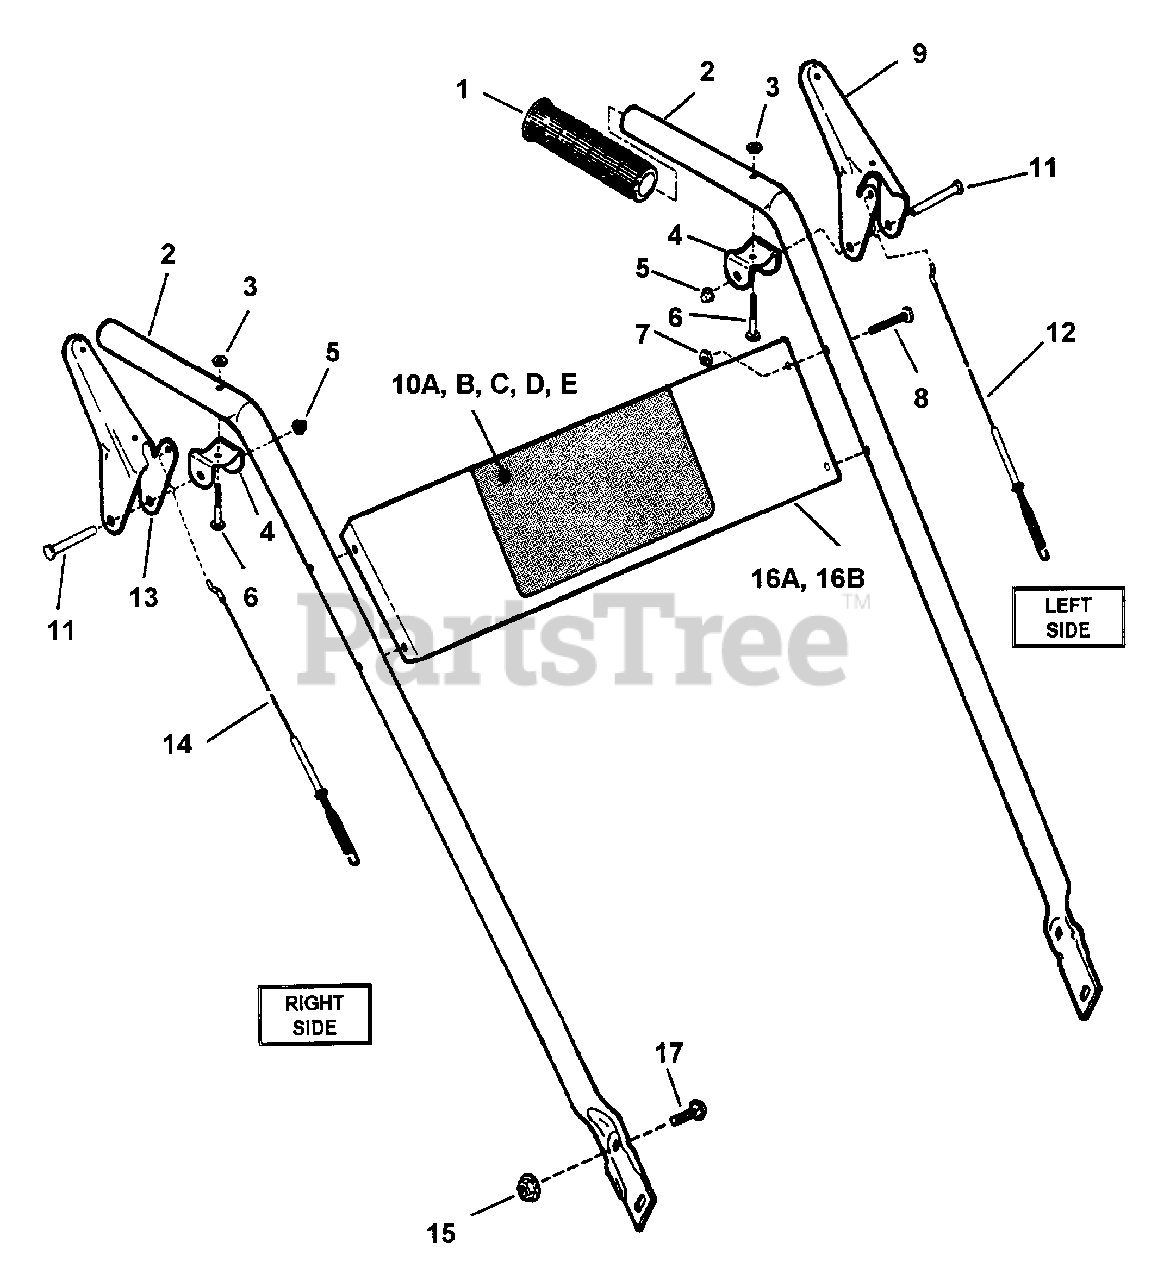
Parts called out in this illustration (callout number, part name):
1	GRIP, Handle
2	BAR, Handle (Right Hand)
3	NUT, 1/4-28 Hex Top Lock
4	BRACKET, Handle
5	NUT, 1/4 Push
6	SCREW, 1/4-28 x 1-3/8" Hex Head Cap, Grade 5
7	NUT, 5/16-18 Hex Center Lock, Grade B
8	SCREW, 5/16-18 x 1-1/2" Hex Head Cap, Grade 5
9	HANDLE, Left Side
10A	DECAL, Snapper (I4223 Model)
10B	DECAL, Snapper (I6223 Model)
10C	DECAL, Snapper (I55223 Model)
10D	DECAL, Snapper (EI55223 Model)
10E	DECAL, Snapper (I5223 Model)
11	PIN, 1/4x 1-7/8" Clevis
12	CABLE, Clutch Left Side (Short)
13	HANDLE, Right Side
14	CABLE, Auger Right Side (Long)
15	NUT, 5/16-18 Hex Flange Lock, Grade 5
16A	PANEL, Control
16B	PANEL, Control
17	BOLT, 5/16-18 x 5/8" Short Neck Carriage, Grade 5
